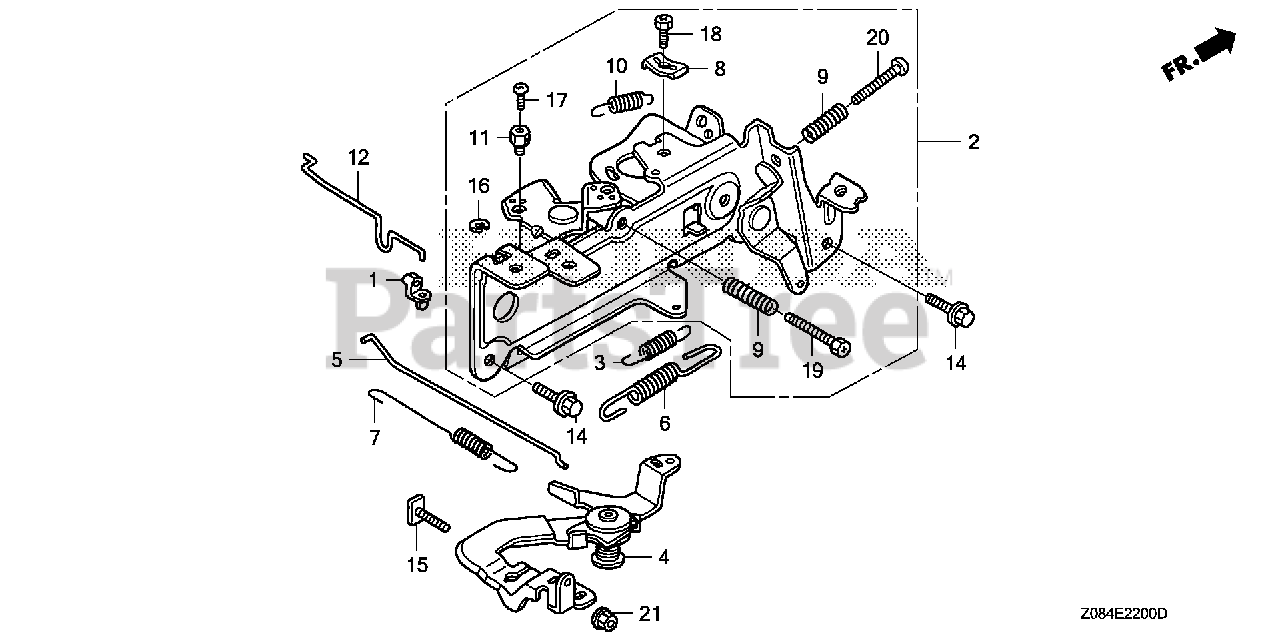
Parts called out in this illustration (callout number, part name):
1	JOINT, ROD
2	CONTROL ASSY. (AUTO THROTTLE)
3	SPRING, STARTER
4	ARM, GOVERNOR
5	ROD, GOVERNOR
6	SPRING, GOVERNOR (MANUAL)
7	SPRING, THROTTLE RETURN
8	HOLDER, CABLE
9	SPRING, CONTROL ADJUSTING
10	SPRING, CABLE RETURN
11	HOLDER, WIRE
12	ROD, CHOKE CONTROL
14	BOLT, FLANGE (6X14) (CT200)
15	BOLT, GOVERNOR ARM
16	CIRCLIP (5MM)
17	BOLT, RECESSED (4X6)
18	BOLT, RECESSED (5X16)
19	BOLT, RECESSED (5X25)
20	SCREW, PAN (5X35)
21	NUT, FLANGE (6MM)
